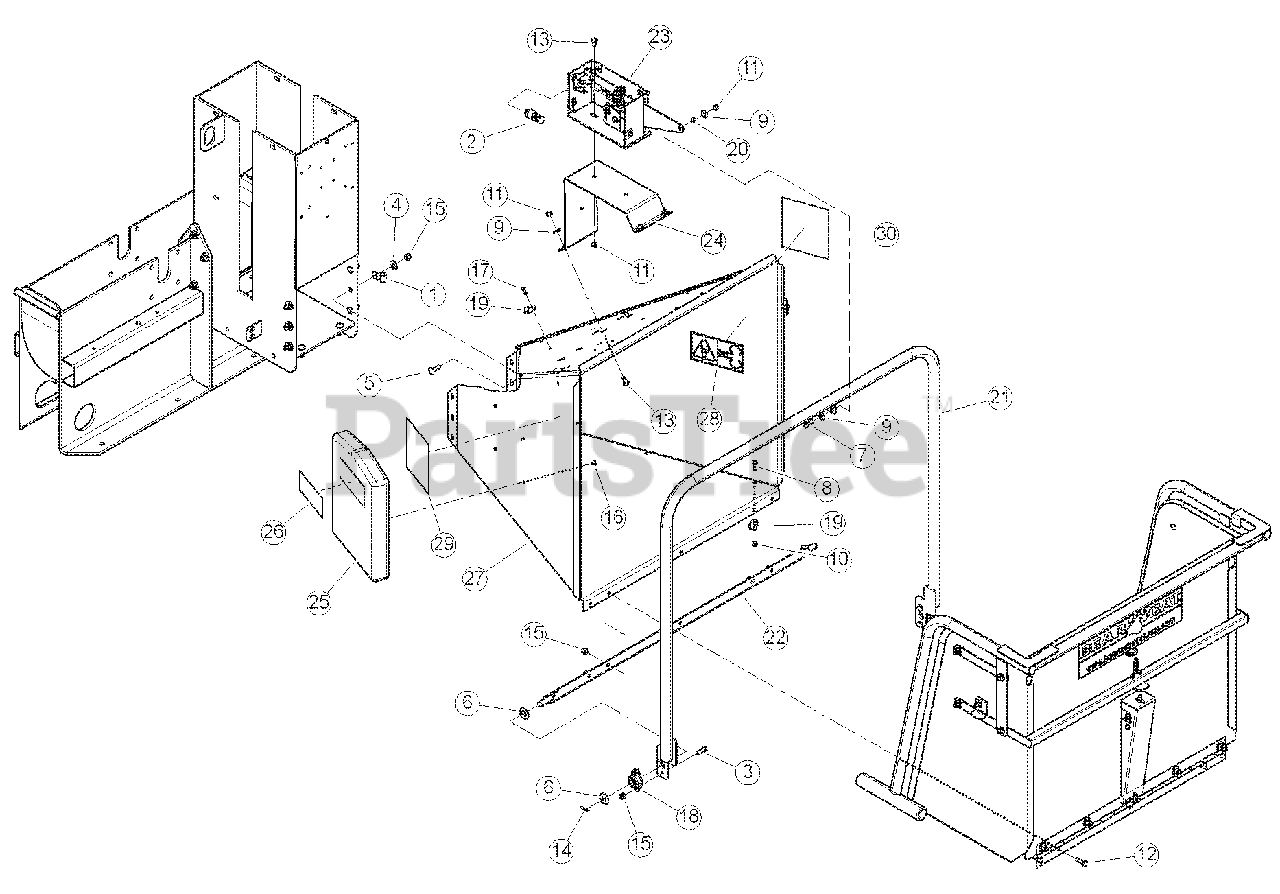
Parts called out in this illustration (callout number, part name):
1	CLAMP, 9/16" COATED
3	BOLT, 3/8 X 1 HEX HD GR5 ZP
4	WASHER, 3/8 FLAT ZP
5	BOLT, 3/8 X 1-1/2 CRG GR5 NC ZP
6	WASHER, 5/8 SAE FLAT ZP
7	BOLT, 5/16 X 1 HHCS GR5 NC ZP
8	BOLT, 1/4 X 1 CRG GR5 NC ZP
9	WASHER, 5/16 FLAT ZP
10	NUT, 1/4 NE NYLOCK ZP
11	NUT, 5/16 NE NYLOCK ZP
12	BOLT, 3/8 X 1-1/4 HEX HD GR5 ZP
13	BOLT, 5/16 X 3/4 CRG GR5 NC ZP
14	PIN, 1/8 X 1.00 ZP COTTER
15	NUT, 3/8 NE NYLOCK ZP
16	RIVET, AL BLIND 1/4 X 1/2 DOME HEAD
17	RIVET, AL BLIND 1/4 X 3/4 DOME HEAD
18	BEARING, SIDE FLANGE MOUNT, 5/8
19	CLAMP, CABLE MOUNT
20	SPACER, IDLER PIVOT
21	WELDMENT, CONTROL ARM
22	WELDMENT, CONTROL PIVOT
23	ASSEMBLY, SWITCH BOX
24	MOUNT, SWITCH BOX
25	ASSEMBLY, MANUAL CONTAINER, SERVICE PART
26	DECAL, MUTILINGUAL MANUAL
27	ASSEMBLY, BIG CHIPPER CHUTE, SERVICE PART
28	DECAL, BLADE DANGER ISO
29	DECAL, FEED POSITION
30	DECAL, FEED POSITION
